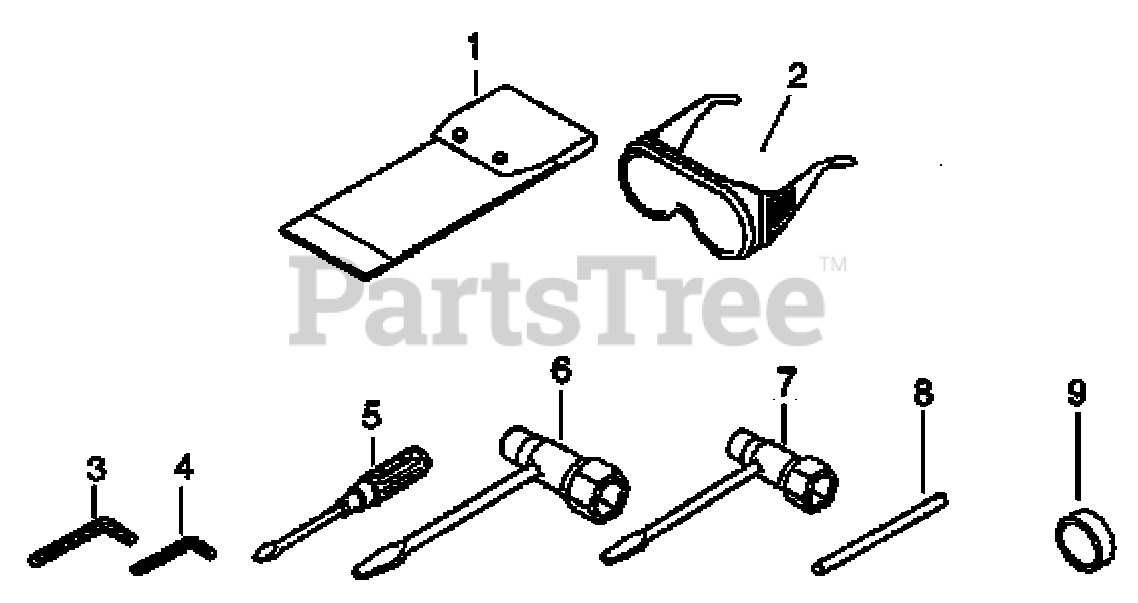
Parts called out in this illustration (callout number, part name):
1	BAG, TOOL
2	GOGGLES
3	HEX KEY - 4mm
4	HEX KEY - 3mm
5	SCREWDRIVER
6	T-WRENCH - 17X19mm
7	T-WRENCH - 13X19mm
8	ROD, LOCKING - 5X120mm
9	COLLAR - 20
